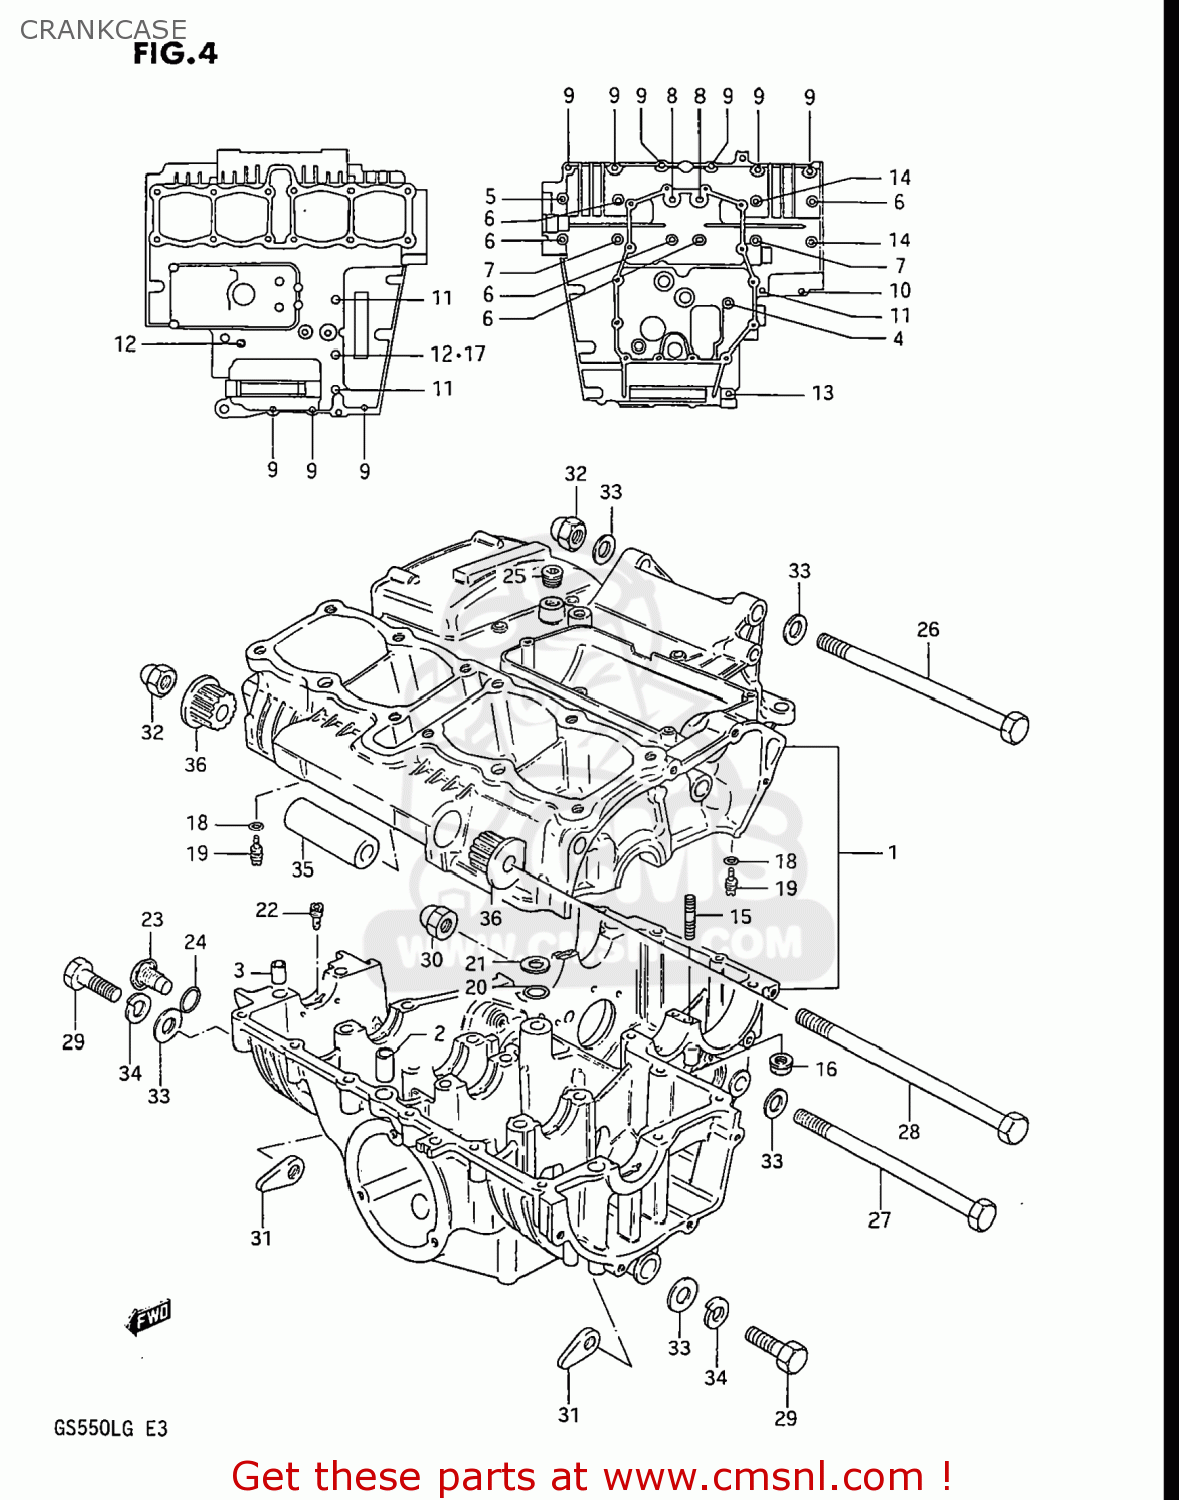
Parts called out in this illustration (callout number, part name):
1	CRANKCASE SET
2	PIN(10.4X13X22)
3	PIN (11X20)(SUS)
4	BOLT(6X100)
5	BOLT
6	BOLT
7	BOLT
8	BOLT
9	BOLT
10	BOLT 6X55
11	BOLT
12	BOLT (5X95)
13	BOLT 8X60
14	BOLT (8X90)
15	STUD BOLT
16	NUT 6MM
17	GASKET(6.2X13X1.2) (NAS)
18	O RING(D:1.2,ID:4)
19	JET,OIL GALLERY
20	O RING(D:3.2,ID:12.9)
21	WASHER,THRUST
22	JET,AIR
23	PLUG
24	O RING(D:2.4,ID:16.8)
25	PLUG
26	BOLT
27	BOLT
28	BOLT
29	BOLT
30	NUT 10MM
31	NUT
32	NUT
33	WASHER
34	LOCK WASHER
35	SPACER (10.2X16X105.5)
36	BUSH
